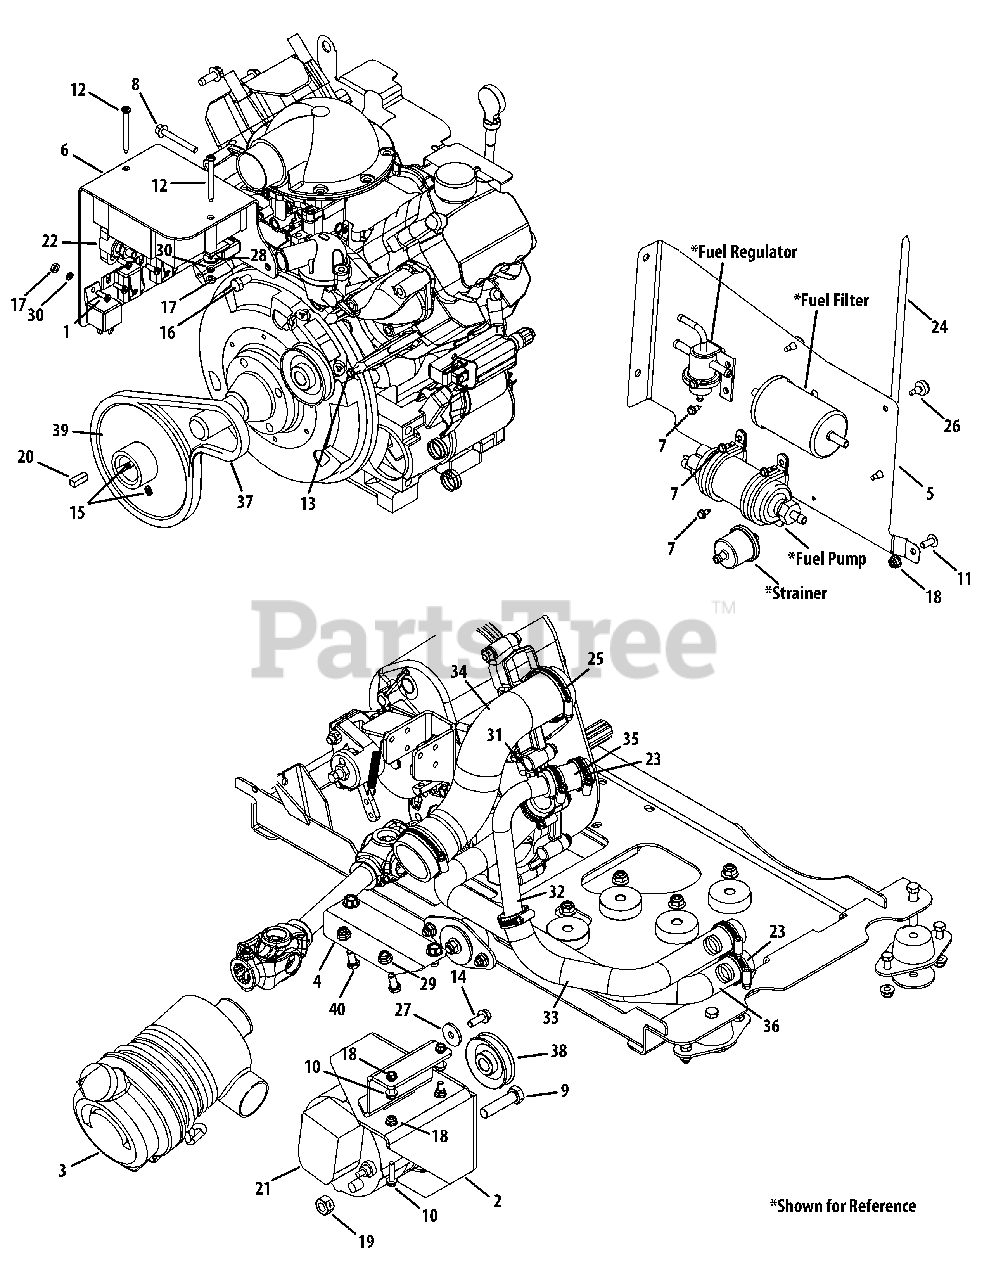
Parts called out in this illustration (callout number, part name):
1	Screw
3	Fltr, Asm, Aircl, 4x4
7	Screw, #10-16 x .500
8	Screw, M6-1
9	Hhcs, 1/2-13 x 2.00
10	Scr, tt, 1/4-20 x 1.00
11	Scr, Mach, 1/4-20 x .625
12	Scr, Mach, #10-32 x 2.00
13	Scr, #10-32 x .625
14	Scr, 5/16-18 x .875
15	Scr, 1/4-20 x .38
16	Hhcs, M8-1.25
17	Nut, Hex, #10-32
18	Nut, Flglk, 1/4-20
19	Nut, Hexlk, 1/2-13
20	Sq key, 1/4 x .75lg
21	Altrnr, Aux, 90 Amp
22	Elec, Power, Distribution Post
23	Clamp, Hose, Adj
24	Tie, Cable
25	Clamp, Hose, Adj
27	Wash, Flat, .344 x 1.125 x .12
28	Wash, Flat, .194 x .62 x .063
29	Nut, Flglk, 5/16-18
30	Wash, Lock
31	Plug, Pipe
32	Tube, Rdtr
34	Hose, Air Inlet
35	Hose, Rdtr, Top Rear
36	Hose, Rdtr, Lower Rear
37	Belt, V-Type
38	Pulley, 2.65 OD x 3L
39	Pulley, 6.00 OD x 1.125
40	Hhcs, 5/16-18 x .75
